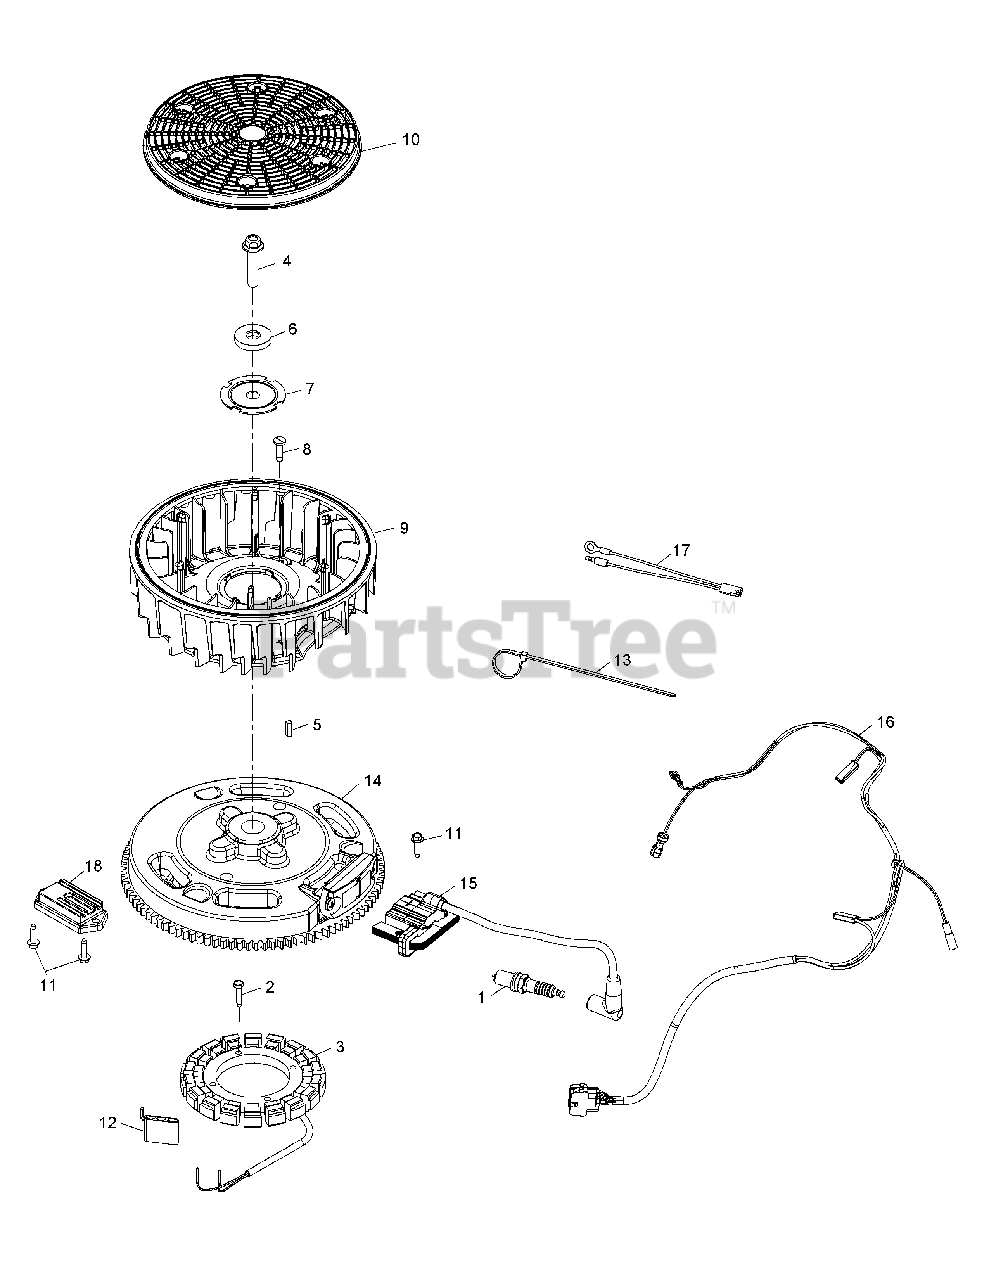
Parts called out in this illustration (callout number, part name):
2	Thread Forming Screw
3	15 Amp Stator Kit
4	Hex Flange Screw
7	Fan Mounting Plate
8	Flywheel Fan Retainer
11	Thread Forming Screw
14	Flywheel Assembly
15	Ignition Module
16	Wiring Harness
18	Rectifier Regulator
